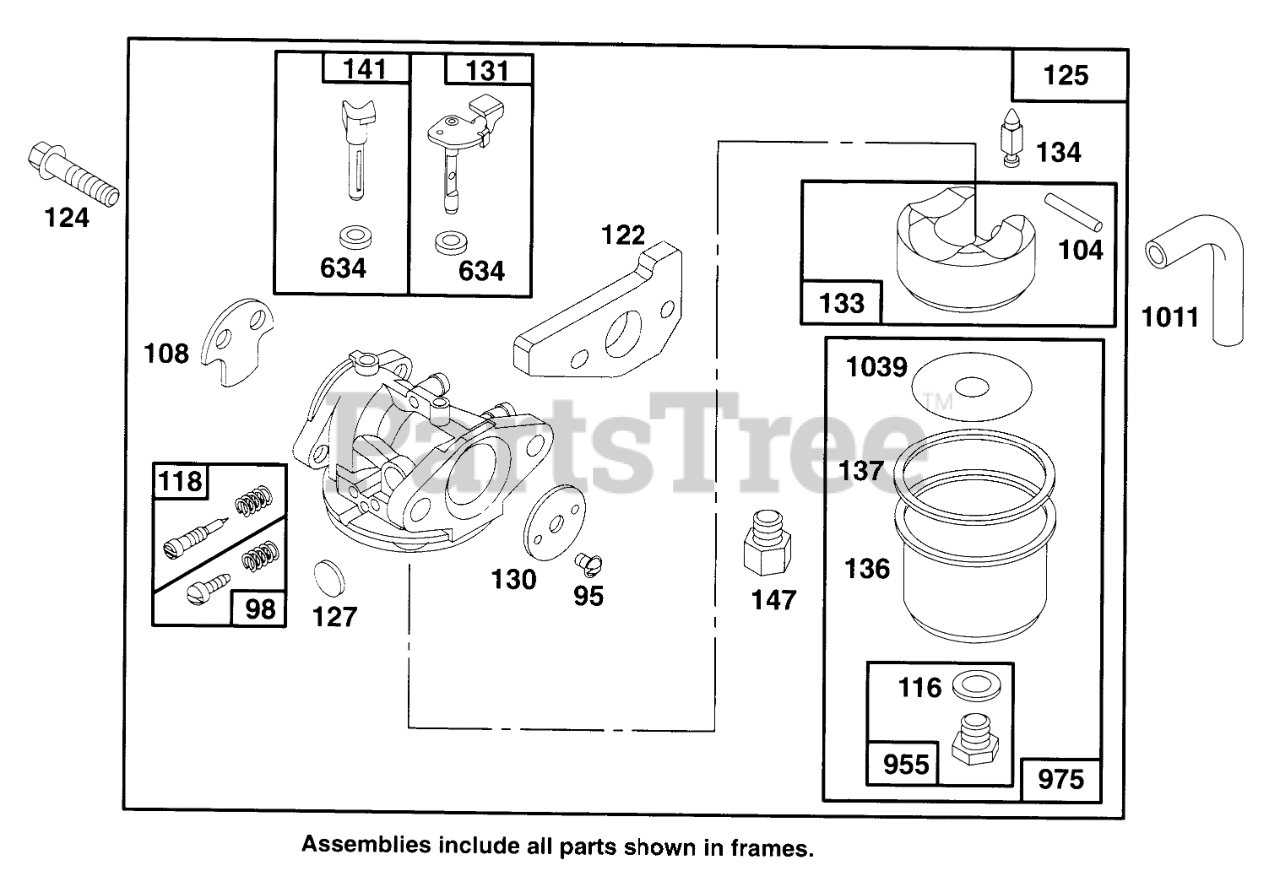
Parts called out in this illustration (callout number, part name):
95	SCREW - ROUND HEAD
98	IDLE ADJUSTING SCREW
104	FLOAT HINGE PIN
108	CHOKE VALVE
116	SEALING GASKET
118	VALVE KIT - NEEDLE
122	ADAPTER ASSEMBLY
124	HEX HEAD SCREW
125	CARBURETOR ASSEMBLY
127	PLUG
130	THROTTLE VALVE
131	THROTTLE SHAFT
133	FLOAT-CARBURETOR
134	Valve-lnlet (Includes Seat)
136	FLOAT BOWL
137	FLOAT BOWL GASKET
141	CHOKE SHAFT
147	JET ADAPTER
634	SEAL WASHER
955	HEX HEAD SCREW
975	CARBURETOR BOWL ASM
1011	VENT TUBE
1039	FLOAT LIMITER
